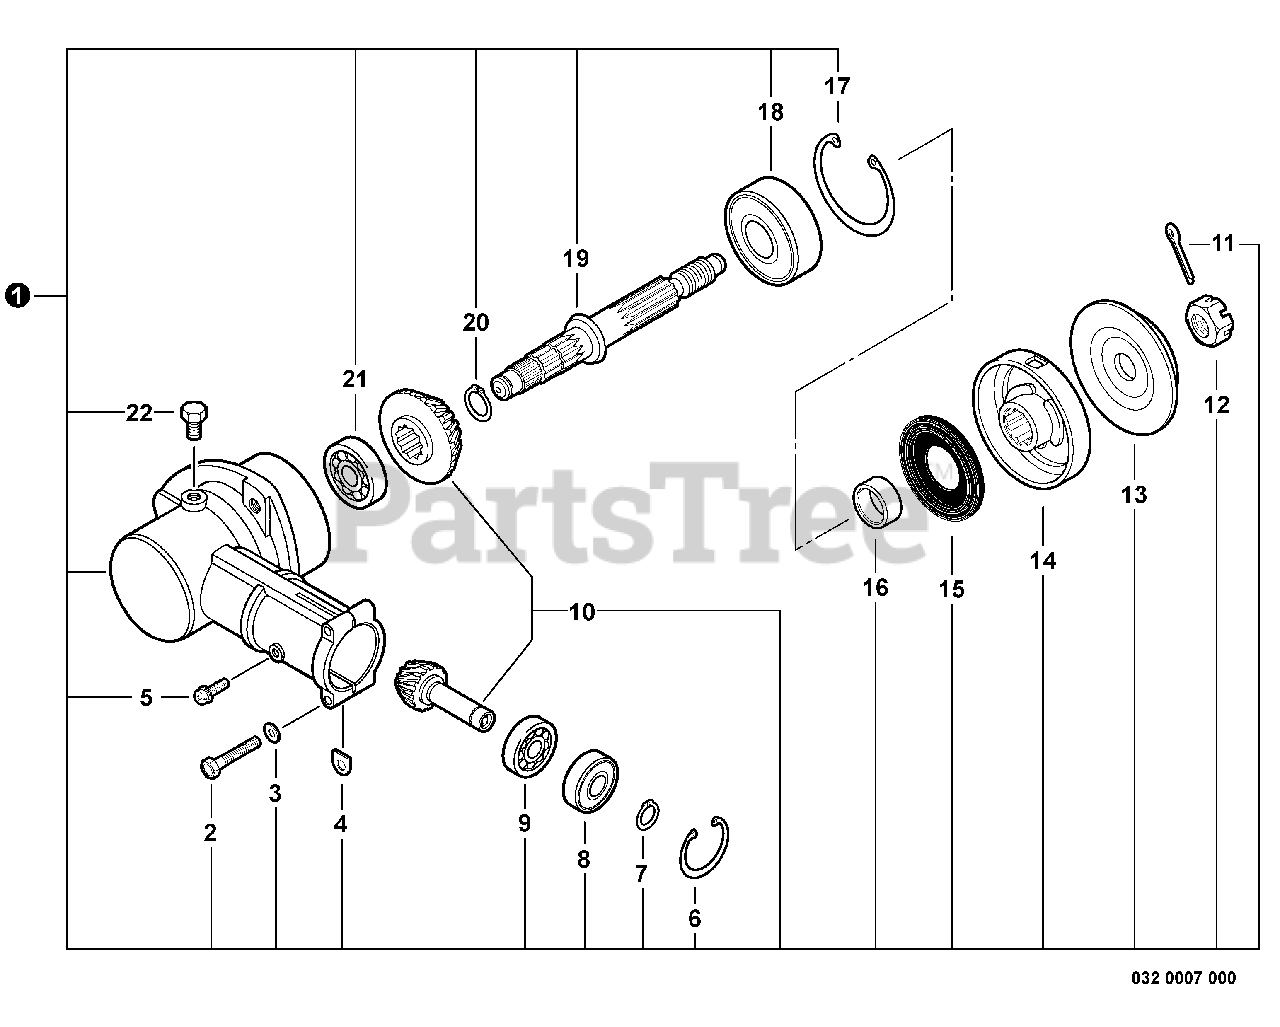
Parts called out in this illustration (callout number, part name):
1	GEAR CASE ASSY
2	BOLT - 5X30
3	WASHER - 5
5	SCREW - 5X10
6	RING, RETAINING - 22
7	RING, RETAINING - 10
8	BEARING, BALL - 6900Z
9	BEARING, BALL - 6900
10	GEAR SET - BEVEL
11	PIN, SPLIT - 2X22
12	LOCKNUT - LEFT HAND
13	ADAPTOR, BLADE - LOWER
14	ADAPTOR, BLADE - UPPER
15	SEAL, OIL
17	RING, RETAINING - 32
18	BEARING, BALL - 6201
19	GEAR - SHAFT
20	RING, RETAINING - 12
21	BEARING, BALL - 609
22	BOLT - 8X8
